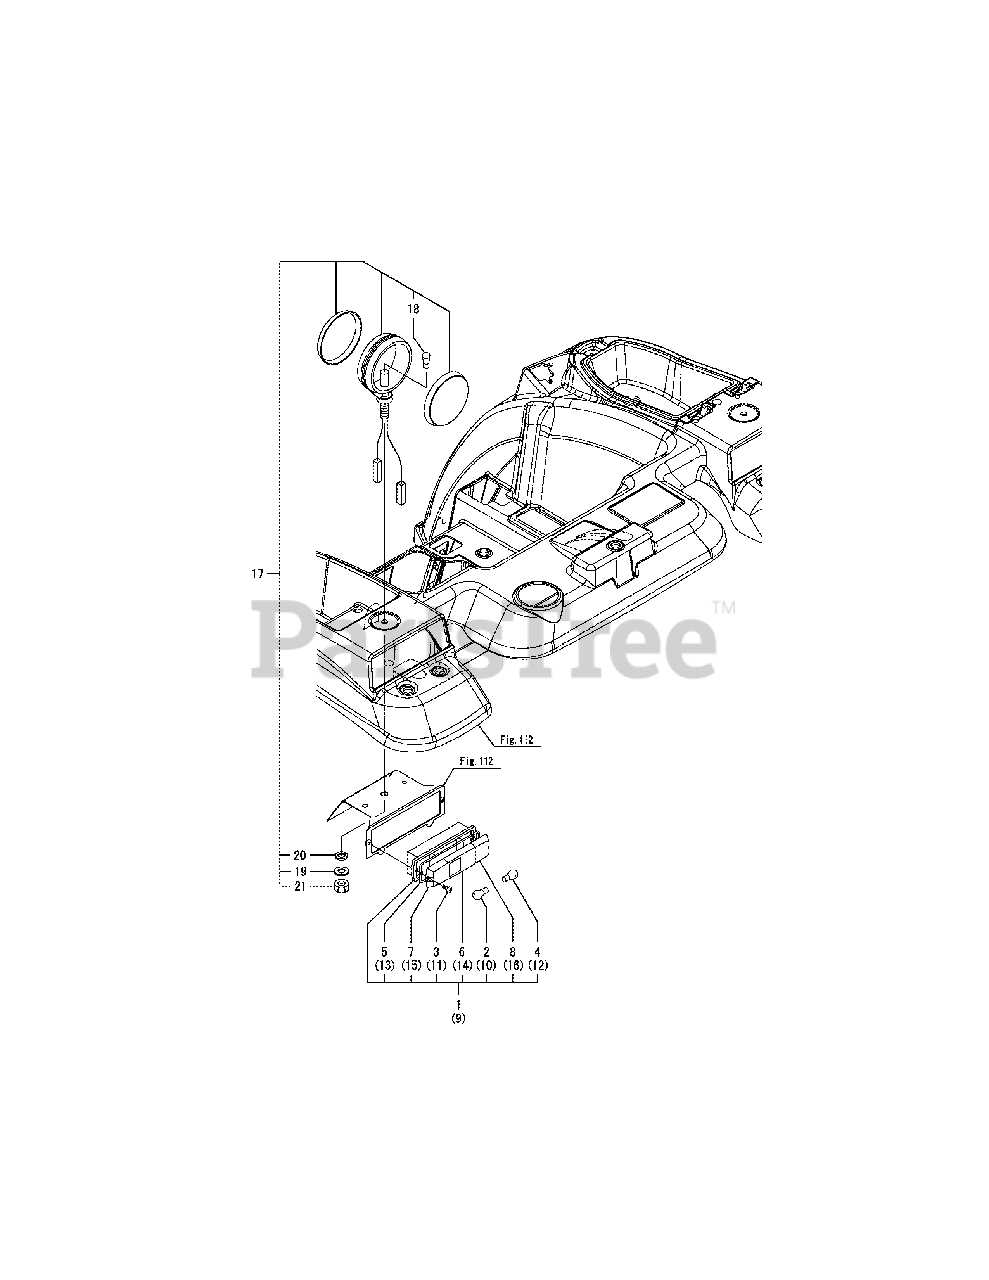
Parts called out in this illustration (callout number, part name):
1	LAMP, REAR COMBI. L
2	VALVE, 12V 21W
4	VALVE,12V21/5W
9	LAMP, REAR COMBI. R
10	VALVE, 12V 21W
12	VALVE,12V21/5W
17	LAMP ASSY, FLASHER
20	WASHER, SPRING 13
21	NUT,1/2-20 UNF
